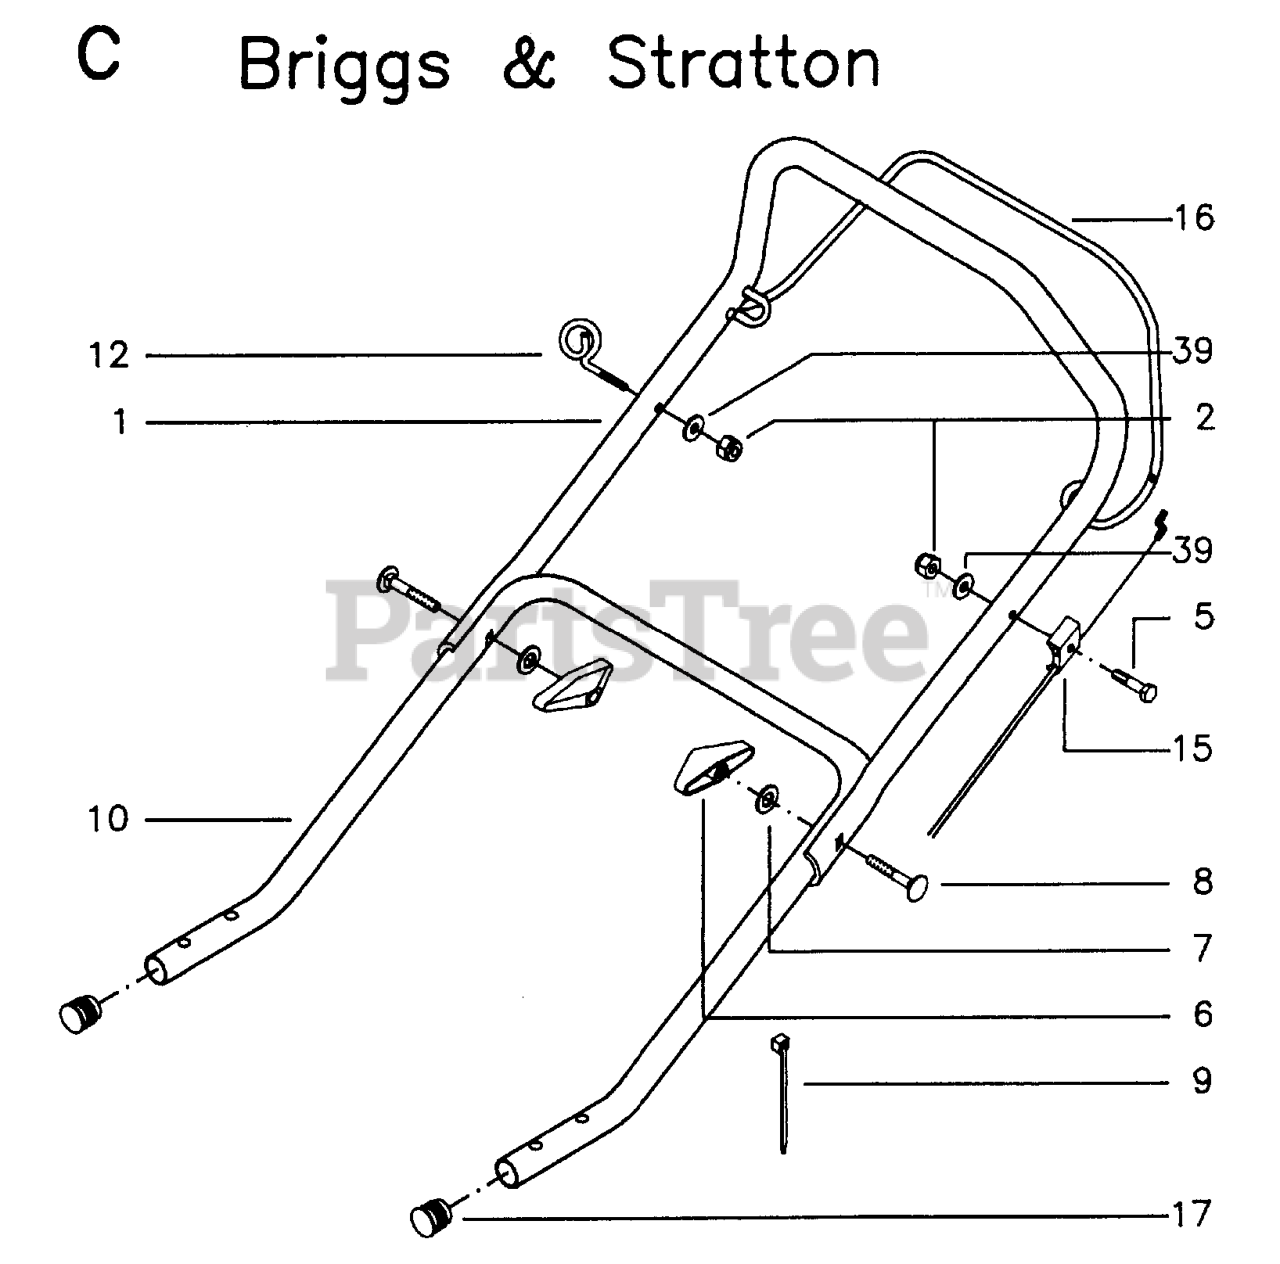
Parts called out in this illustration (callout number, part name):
2	LOCKNUT M6
5	BOLT FLANGE
6	WINGNUT
12	CABLE GUIDE
15	REPL BY 532 85 16-72
